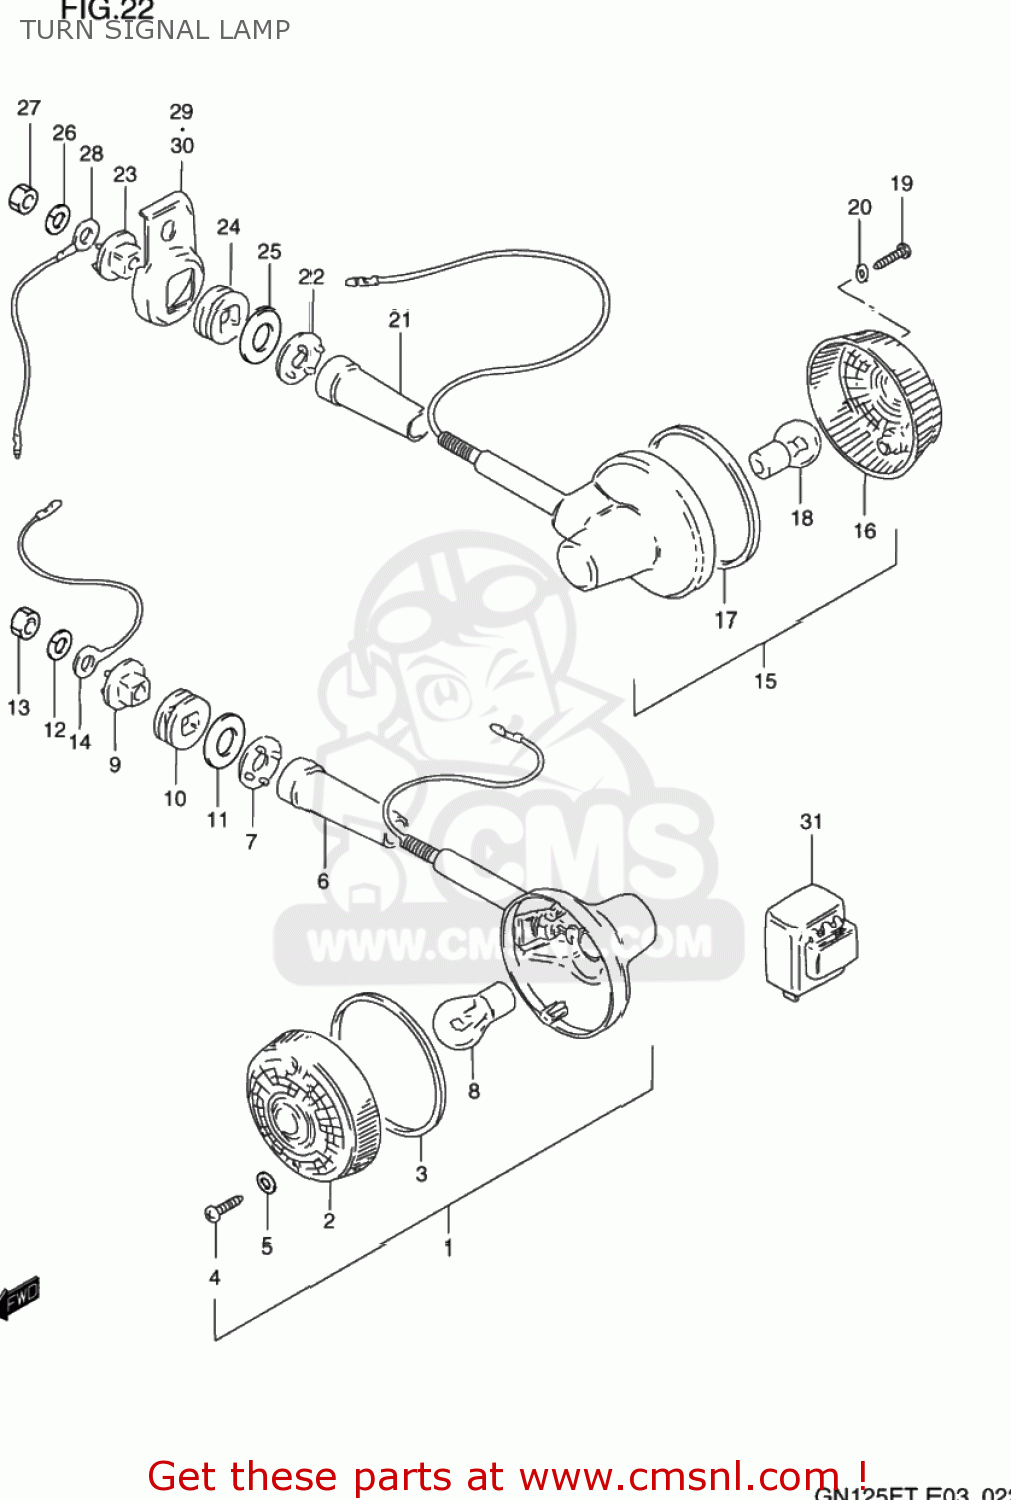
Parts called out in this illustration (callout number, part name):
1	LAMP ASSY,TURNSIGNAL
2	LENS
3	GASKET (NAS)
4	SCREW
5	GASKET (NAS)
6	COVER,STAY
7	SPACER
8	BULB(12V23W,STANLEY,A4577A)
9	SPACER
10	CUSHION
11	WASHER (10.5X30X2.3)
12	LOCK WASHER
13	NUT
14	LEAD WIRE,EARTH
15	LAMP ASSY,RR TURNSIGNAL
16	LENS
17	GASKET (NAS)
18	BULB(12V23W,STANLEY,A4577A)
19	SCREW
20	GASKET (NAS)
21	COVER
22	SPACER
23	SPACER
24	CUSHION
25	WASHER (10.5X30X2.3)
26	LOCK WASHER
27	NUT
28	LEAD WIRE,EARTH
29	BRACKET,RR TURNSIGNAL LAMP,R
30	BRACKET,RR TURNSIGNAL LAMP,L
31	RELAY ASSY,TURNSIGNAL
